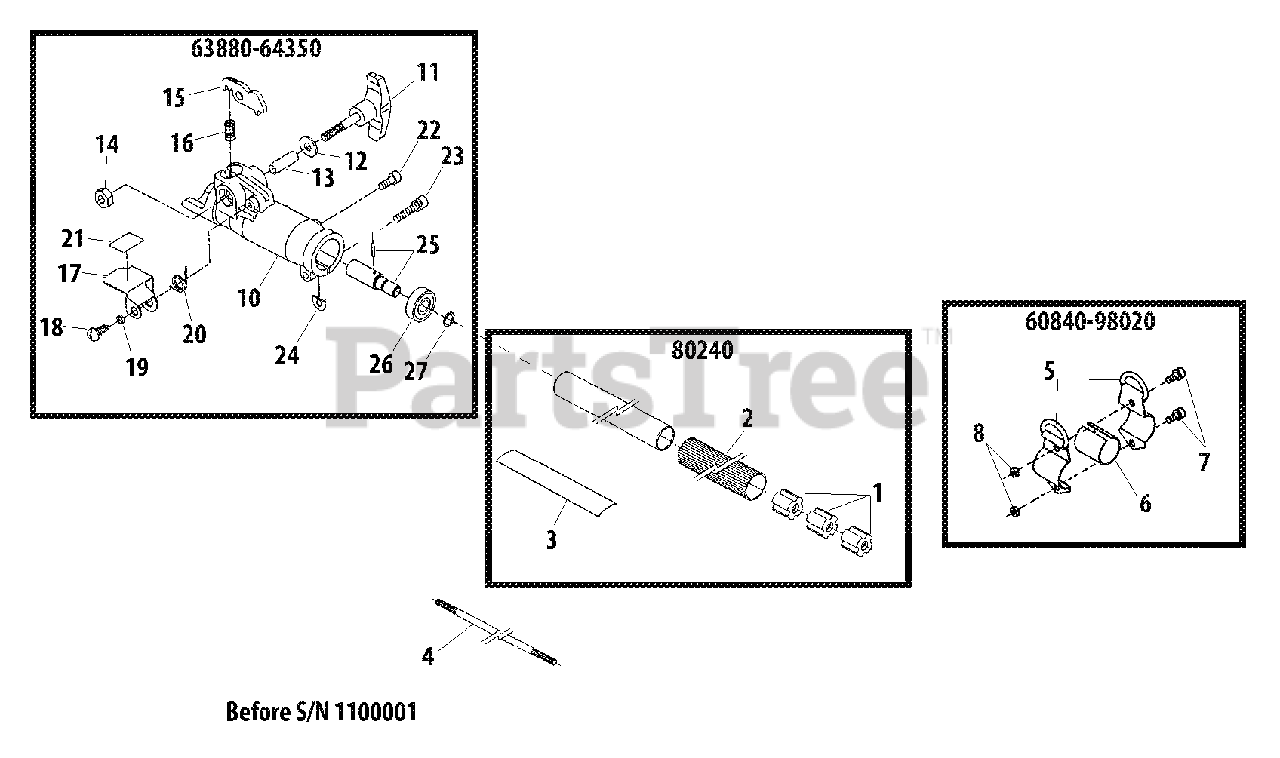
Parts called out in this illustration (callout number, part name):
1	BUSHING
2	GRIP
3	LABEL - CAUTION
4	PIPE, MAIN
6	SHIM
7	SCREW - 5X12
10	COUPLER
11	KNOB
12	WASHER
13	COLLAR
14	NUT
15	LEVER, LOCK
16	SPRING
17	COVER
18	SCREW
19	COLLAR
20	SPRING
21	LABEL - LATCH INSTRUCTION
22	SCREW - 5X12
23	SCREW - 5X25
24	SHIM
25	CONNECTOR, SHAFT
26	BEARING, BALL - 609ZZ
27	RING, RETAINING
60840-98020	HANGER ASSY
63880-64350	COUPLER ASSY
80240	MAIN PIPE ASSY
